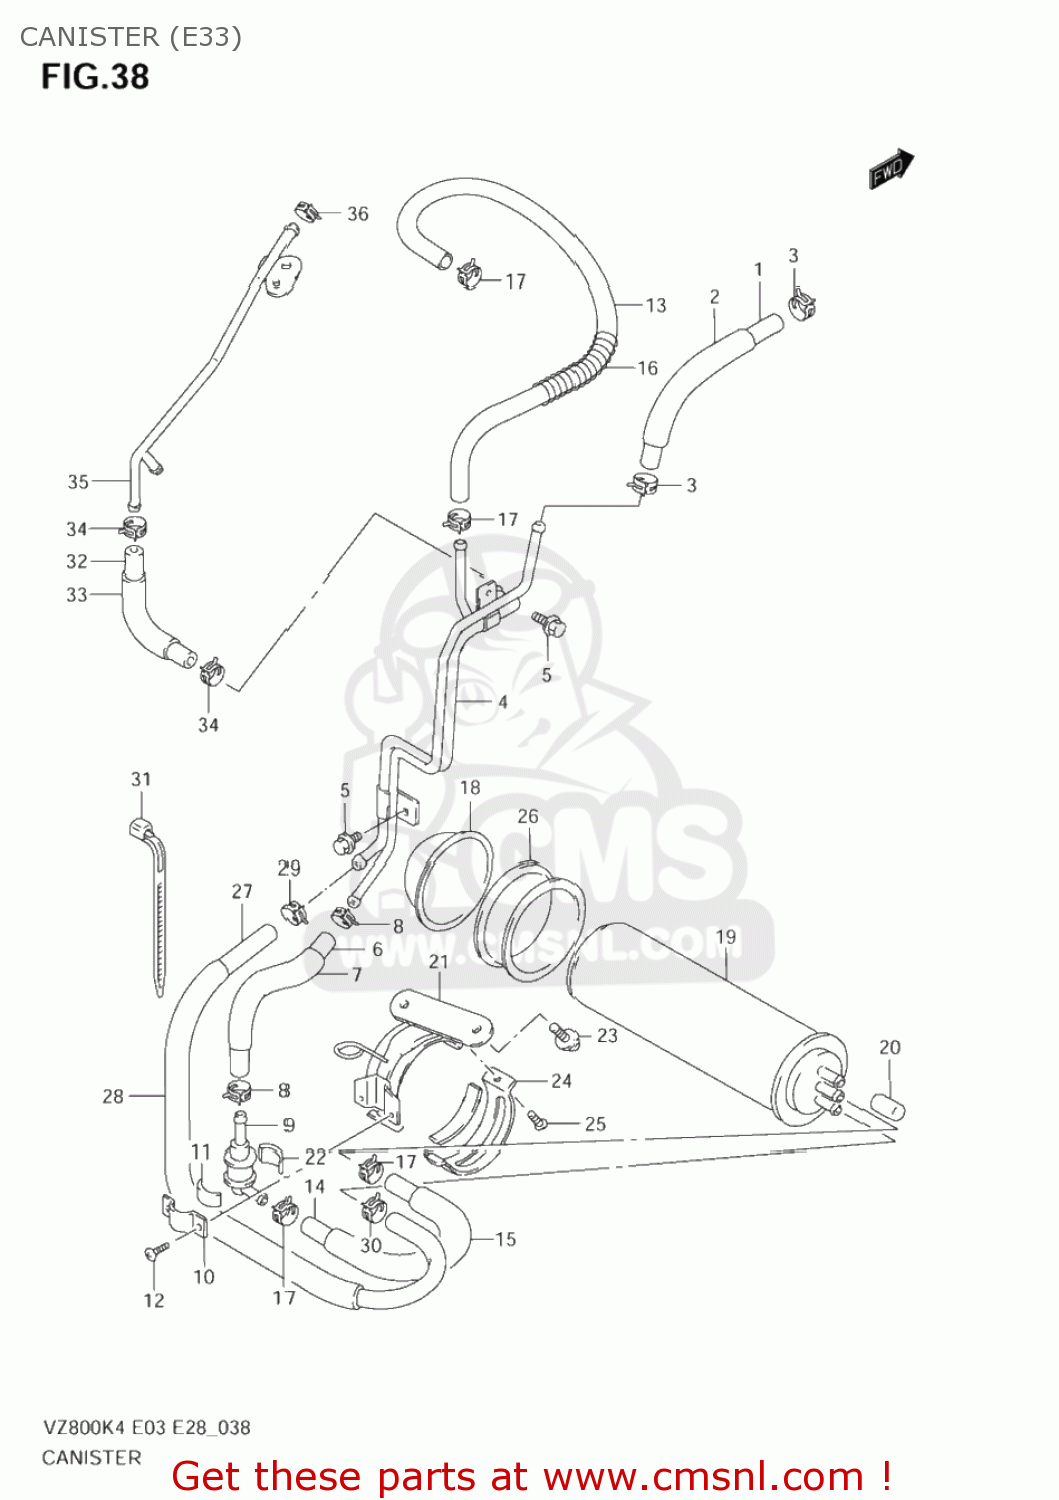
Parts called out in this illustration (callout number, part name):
1	HOSE TANK & BREATHER VALVE
2	SPRING
3	CLIP
4	PIPE,TANK & BREATHER
5	BOLT
6	HOSE(5.4X11.4X600)
7	SPRING
8	CLIP
9	VALVE,FUEL TANK BREATHER
10	PLATE,FUEL TANK BREATHER NO.2
11	CUSHION
12	SCREW
13	HOSE(5.4X11.4X2000)
14	HOSE,CSTR & BREATHER VALVE
15	SPRING
16	(CA) SPRING
17	CLIP
18	CAP,CANISTER
19	CANISTER ASSY,CHARCOAL
20	CAP,OD:11.5
21	BRACKET,CANISTER
22	CUSHION
23	BOLT
24	HOLDER,CANISTER
25	SCREW 6X10
26	CUSHION,CANISTER
27	HOSE,CSTR & CARB
28	SPRING
29	CLIP
30	CLIP
31	CLAMP(L:125)
32	HOSE(5.4X11.4X600)
33	SPRING
34	CLIP
35	PIPE,CSTR & CARB
36	CLIP
